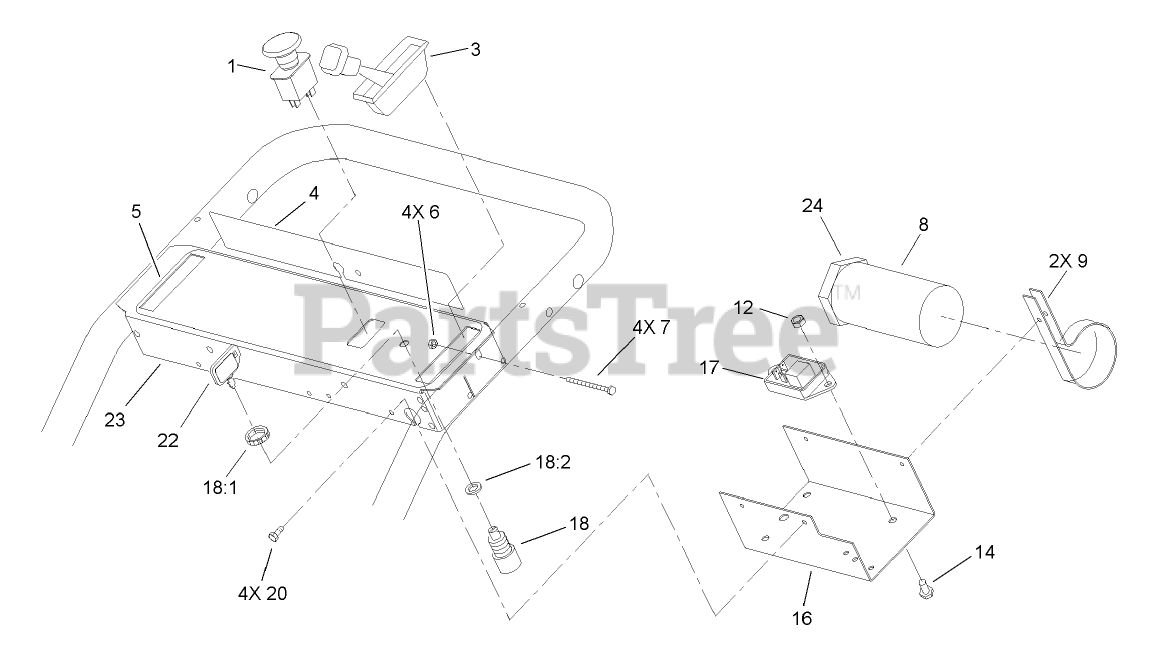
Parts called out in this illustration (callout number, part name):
1	SWITCH-PTO
3	CONTROL-THROTTLE
4	DECAL-WARNING
5	DECAL-PANEL, CONTROL
6	NUT-LOCK, NI
7	SCREW-SHH
8	TUBE-MANUAL
9	CLAMP-R
12	NUT-LOCK, NI
14	SCREW-HH
16	PANEL-BOTTOM
17	MODULE-DELAY
18	SWITCH-STARTER
18:1	NUT-HH
18:2	WASHER-TOOTH, INTERNAL
20	SCREW-HWHTF
22	KEY-IGNITION
23	PANEL-CONTROL
24	CAP-HOUSING
